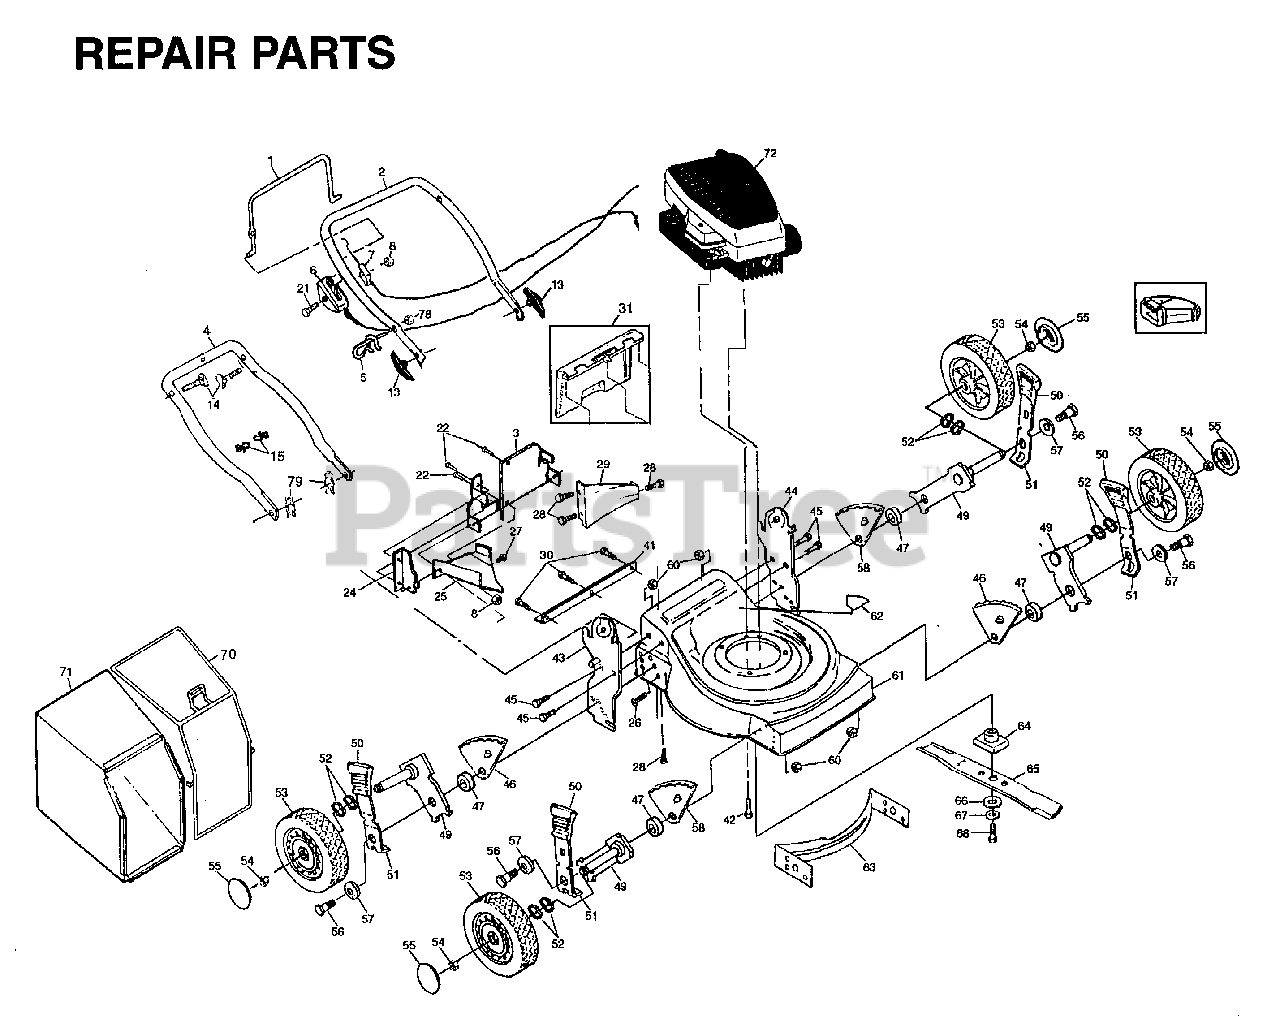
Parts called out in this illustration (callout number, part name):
1	CONTROL BAR/BLACK
2	UPPER HANDLE
5	ROPE GUIDE
6	THROTTLE CONTROL
7	ENGINE ZONE CONTROL CABLE
8	NUT.CROWNLOCK.1/4
13	HANDLE KNOB
14	HANDLE BOLT
15	CLIP CABLE SNAP
21	SCREW 1/4-20 X 2.12
22	RIVET BLIND
24	SIDE BAFFLE
26	HINGE SCREW
27	SCREW.HXTAP.10-24
29	REAR BAFFLE
31	REAR DOOR ASSEMBLY KIT
43	HANDLE BRACKET ASSEMBLY-RIGHT
44	HANDLE BRACKET ASSEMBLY - LEFT
45	BOLT
47	RP SPACER HT ADJ
49	AXLE ARM
50	SELECTOR KNOB
51	SELECTOR SPRING
52	WAVE WASHER
53	WHEEL.8X2.PR.LP.RAD.GREY
54	HEX FLANGE LOCKNT
56	BOLT
57	BELLEVILLE WASHER
62	DECAL MOWER CUT/FINGER
64	BLADE ADAPTOR
65	BLADE.20.MULCH.(50DK,6020MD)
66	WASHER,HARDEN
67	LOCKWASHER
68	SCREW, HEX HD 3/8-24 X 1-3/8
70	CATCHER FRAME
78	NUT.CROWNLOCK.1/4
79	HAIRPIN COTTER
